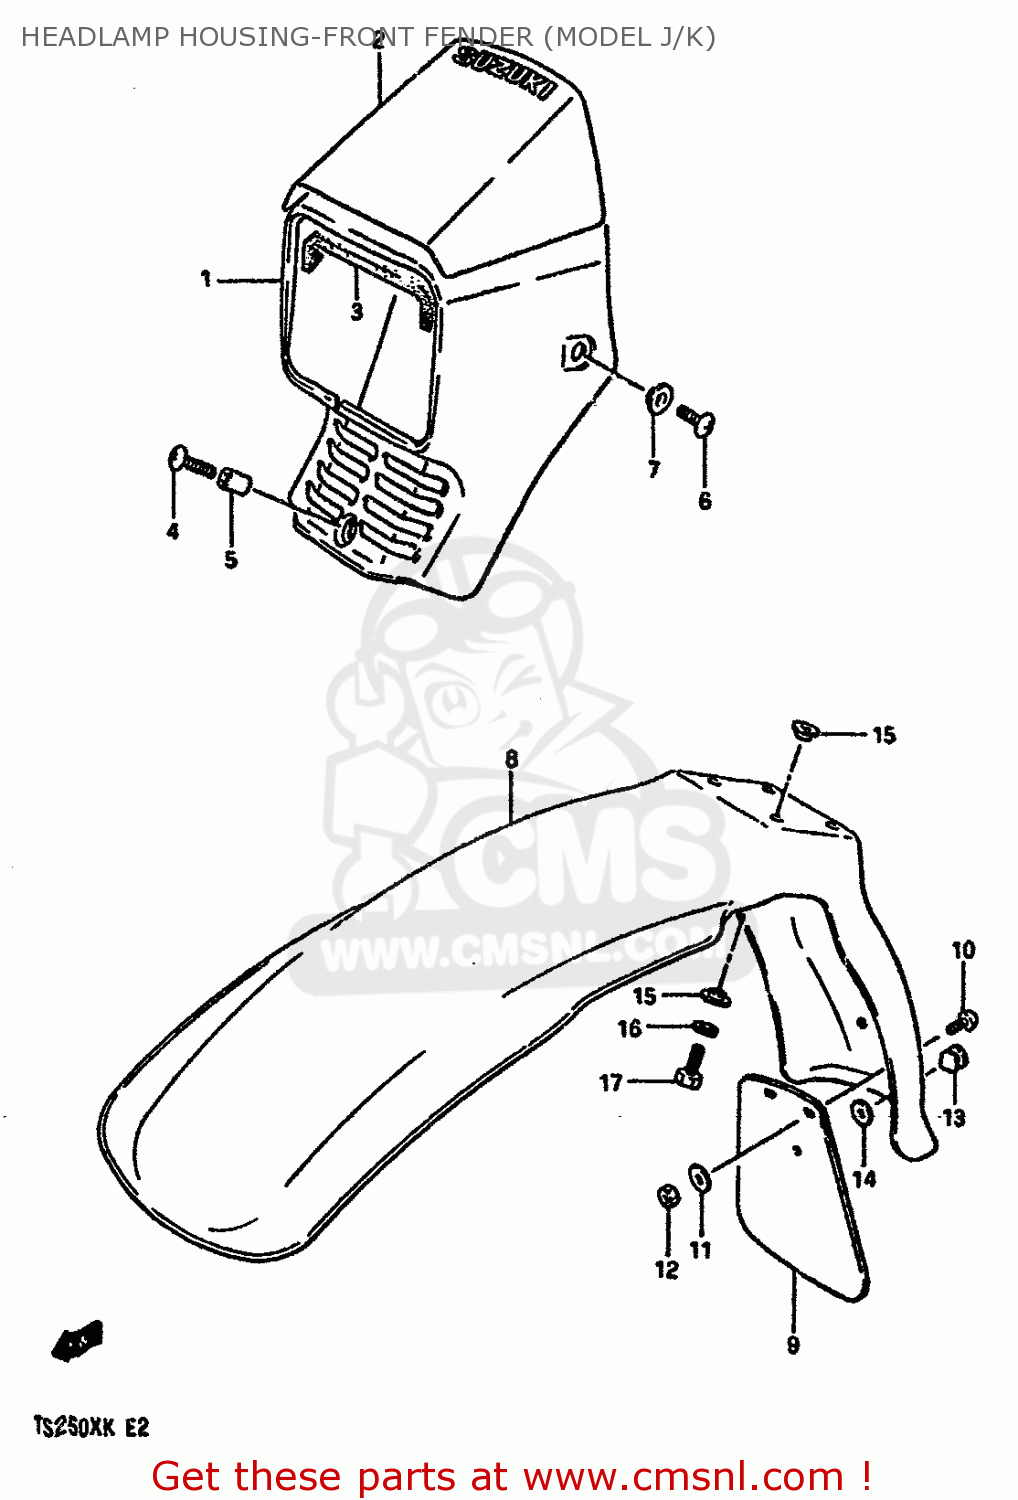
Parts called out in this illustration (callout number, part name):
1	COVER,HEADLAMP (WHITE)
2	TAPE SET
3	CUSHION
4	SCREW
5	SPACER(6.8X10X24.2)
6	SCREW 6X12
7	WASHER
8	FENDER,FRONT (WHITE)
9	MUD FLAP
10	SCREW 5X10
11	WASHER(5.2X16X1)
12	NUT 5MM
13	CUSHION
14	WASHER
15	WASHER
16	WASHER,LOCK
17	BOLT
